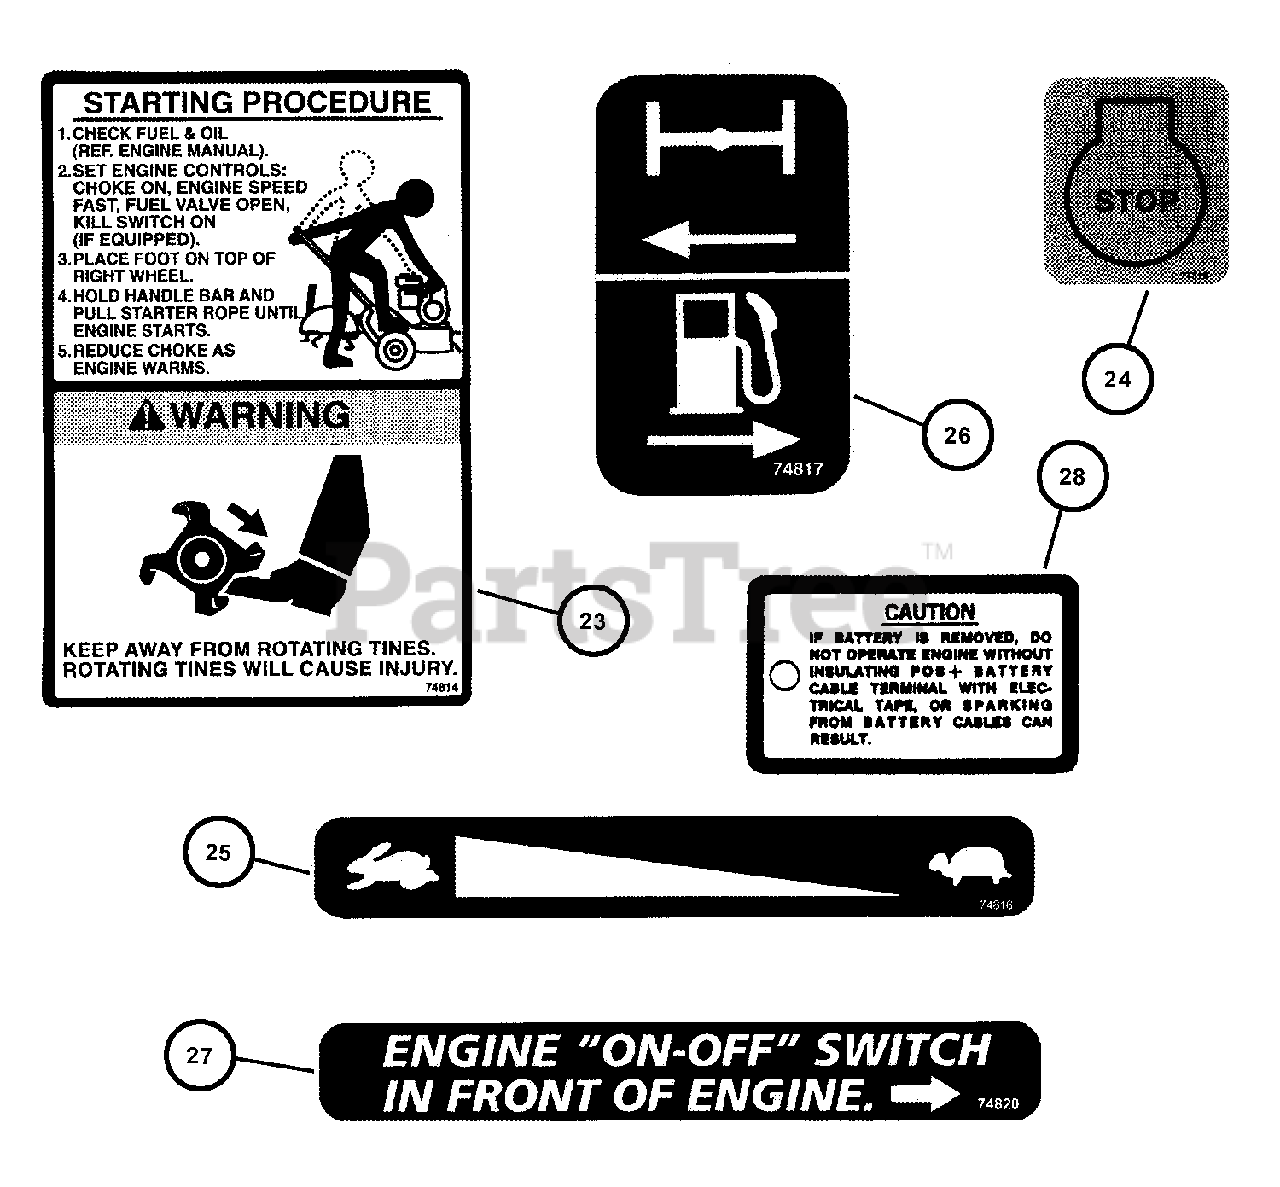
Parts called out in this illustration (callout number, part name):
23	DECAL, Warning and Starting Instruction
24	DECAL, Stop
25	DECAL, Speed
26	DECAL, Choke and Fuel
27	DECAL, Engine On-Off
28	DECAL, Caution Tag
